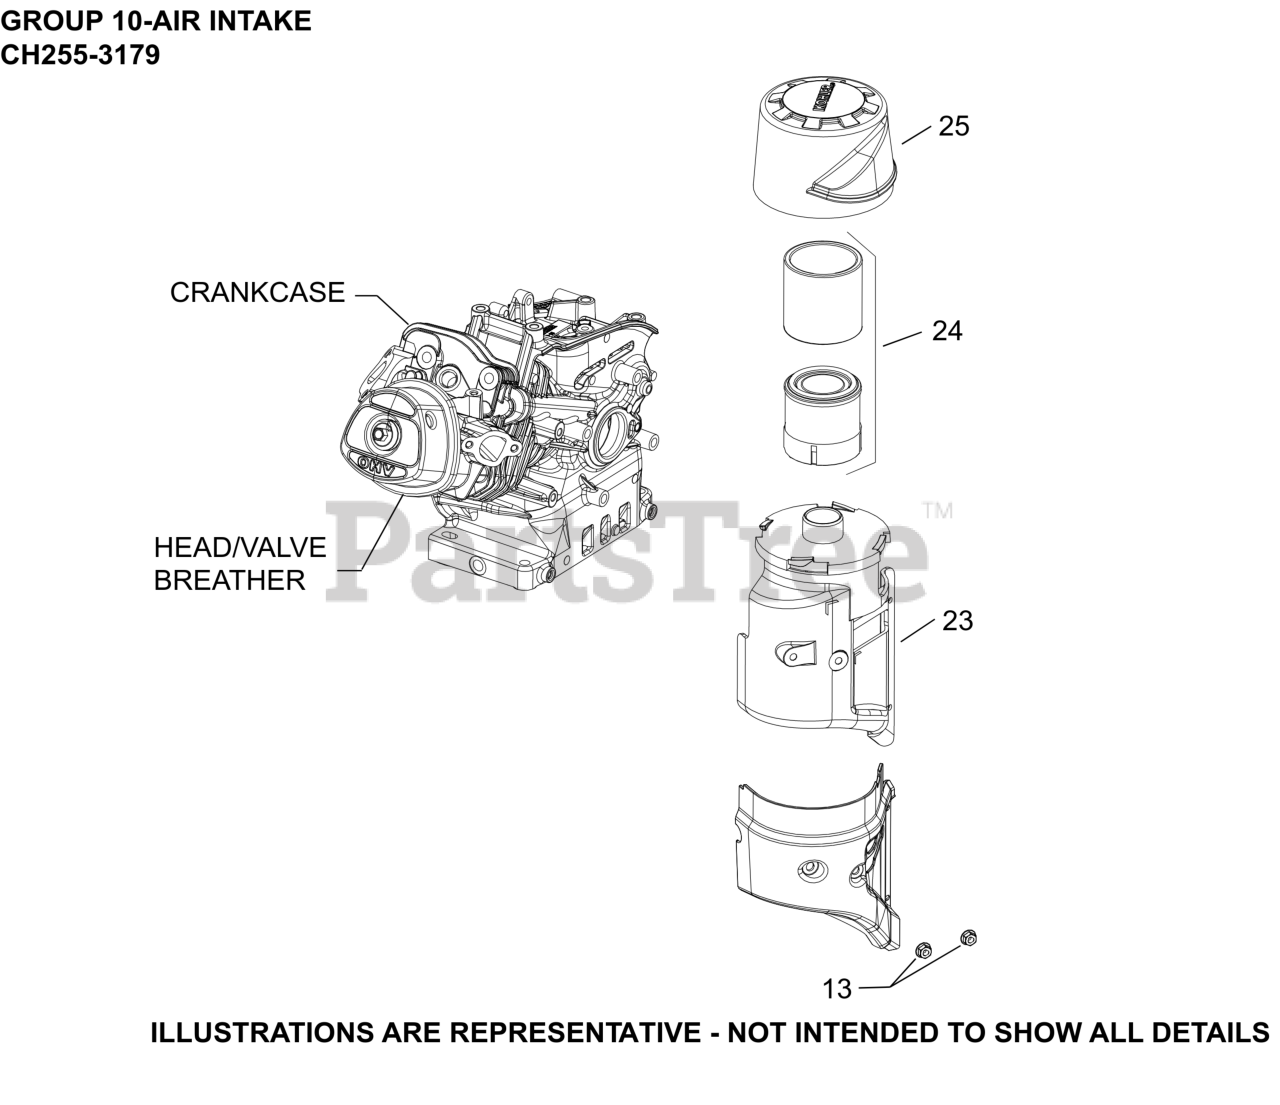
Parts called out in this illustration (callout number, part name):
13	NUT, HEX FLANGE LOCK (M6)
23	BASE, AIR CLEANER ASSEMBLY
24	ELEMENT, FILTER ASSEMBLY
25	COVER, AIR CLEANER ASSEMBLY
